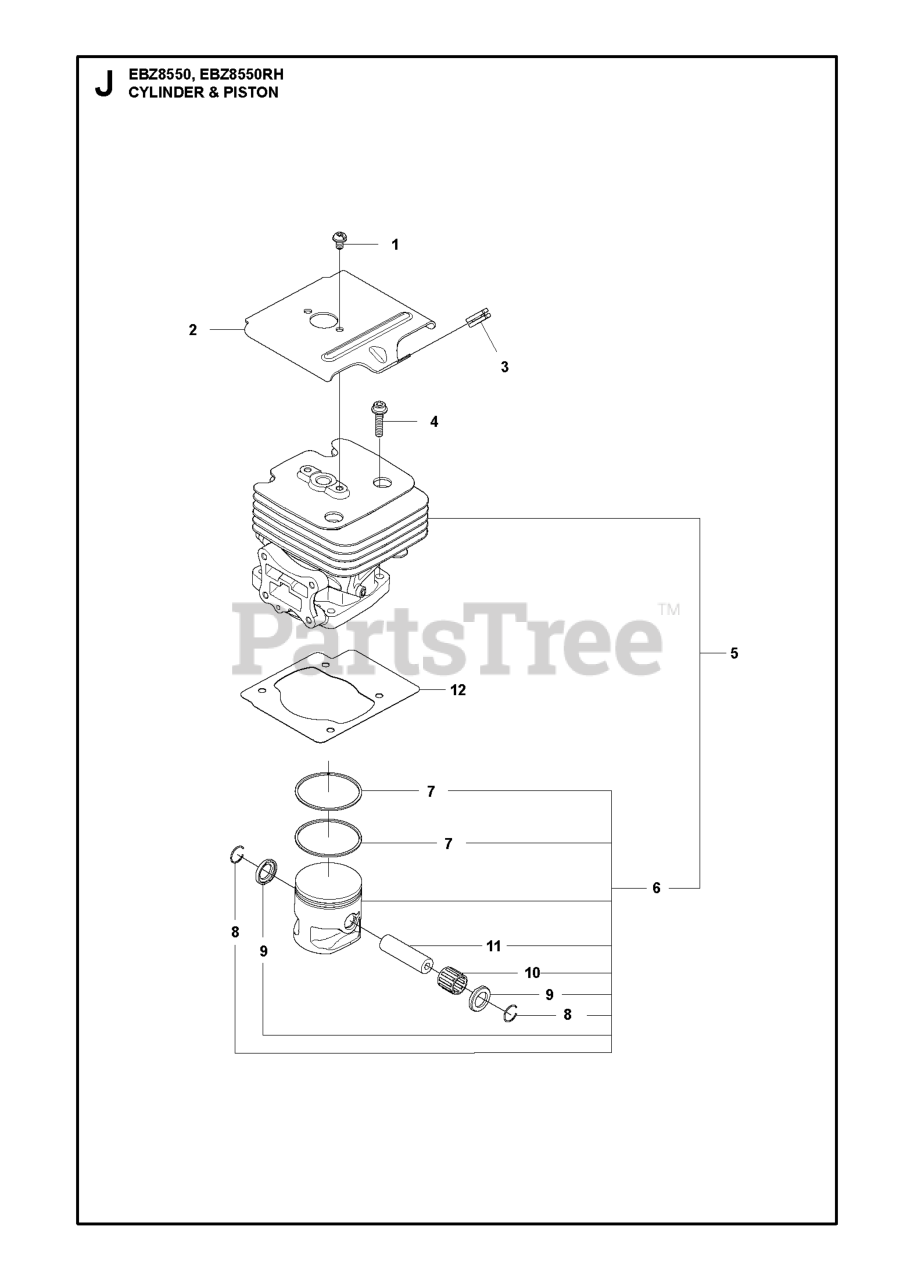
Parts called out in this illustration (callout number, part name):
4	BOLT
5	CYLINDER ASSY
7	PISTON RING
8	SNAP RING
10	BEARING
11	PISTON PIN
